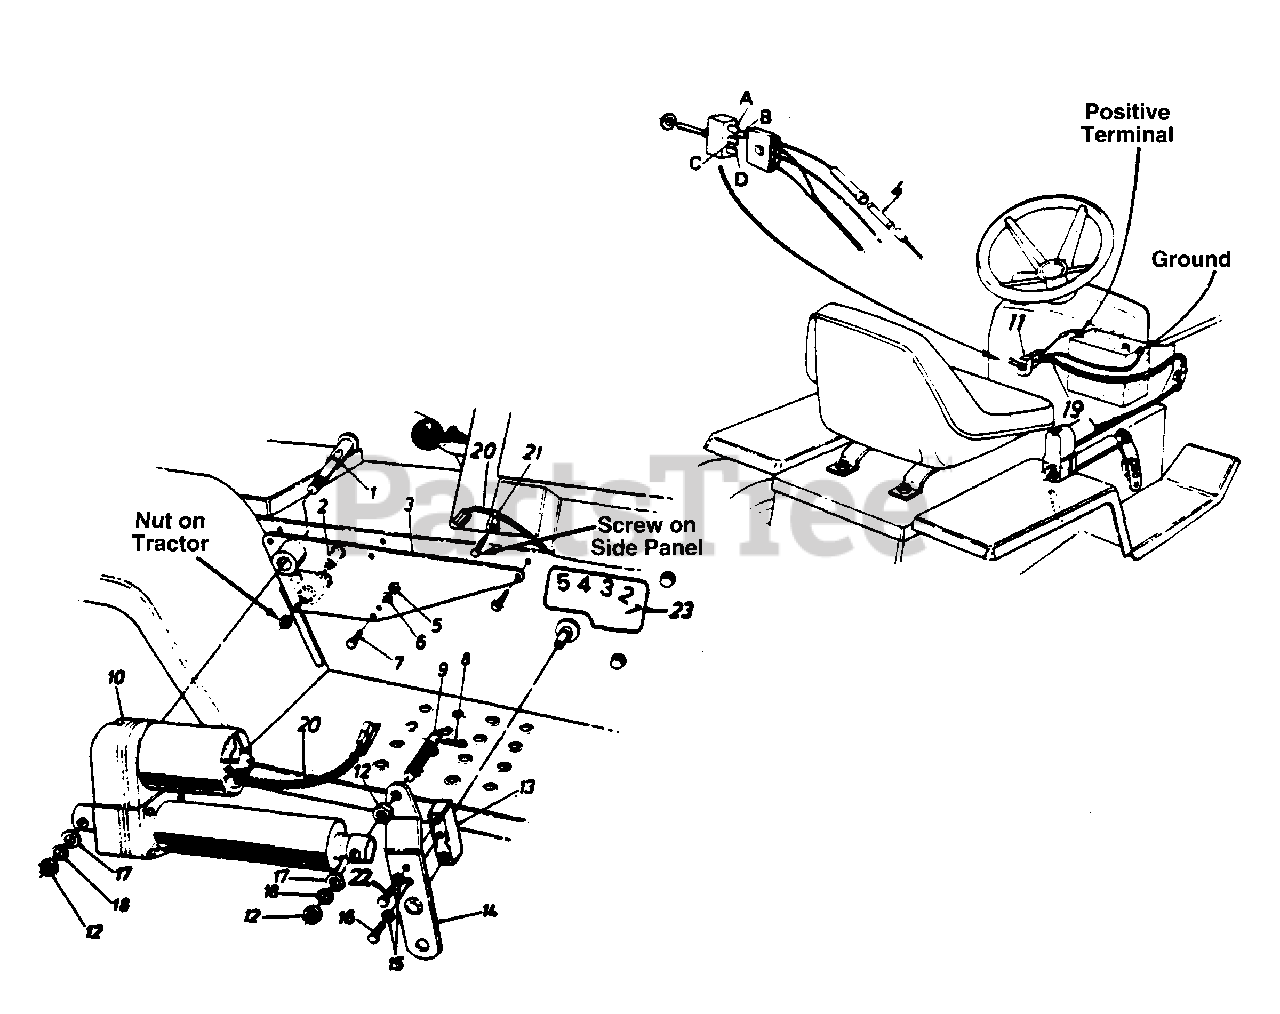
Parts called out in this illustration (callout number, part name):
2	Shld. Bolt .626" Dia. x .96"
5	Hex Nut 1/4-28 Thd.
6	L-Wash. 1/4" I.D.
7	Hex Bolt 1/4-28 x .75" Lg. (Grade 5)
9	Indicator & Mtg. Pin
10	Electric Actuator
11	Toggle Switch
12	Hex Jam Nut 1/2-13 Thd.
13	Lift Shaft Drive
16	Hex Bolt 5/16-24 x 1.0" Lg. (Grade 5)
17	Fl-Wash. .53" I.D. x .93" O.D.
18	L-Wash. 1/2" I.D.
19	Wire Harness
20	Plastic Tubing - 7"
22	Hex Bolt 5/16-18 x 1" Lg. (Grade 5)
23	Label
A	Blue Wire
B	Yellow Wire
C	Black Wire
D	Red Wire
